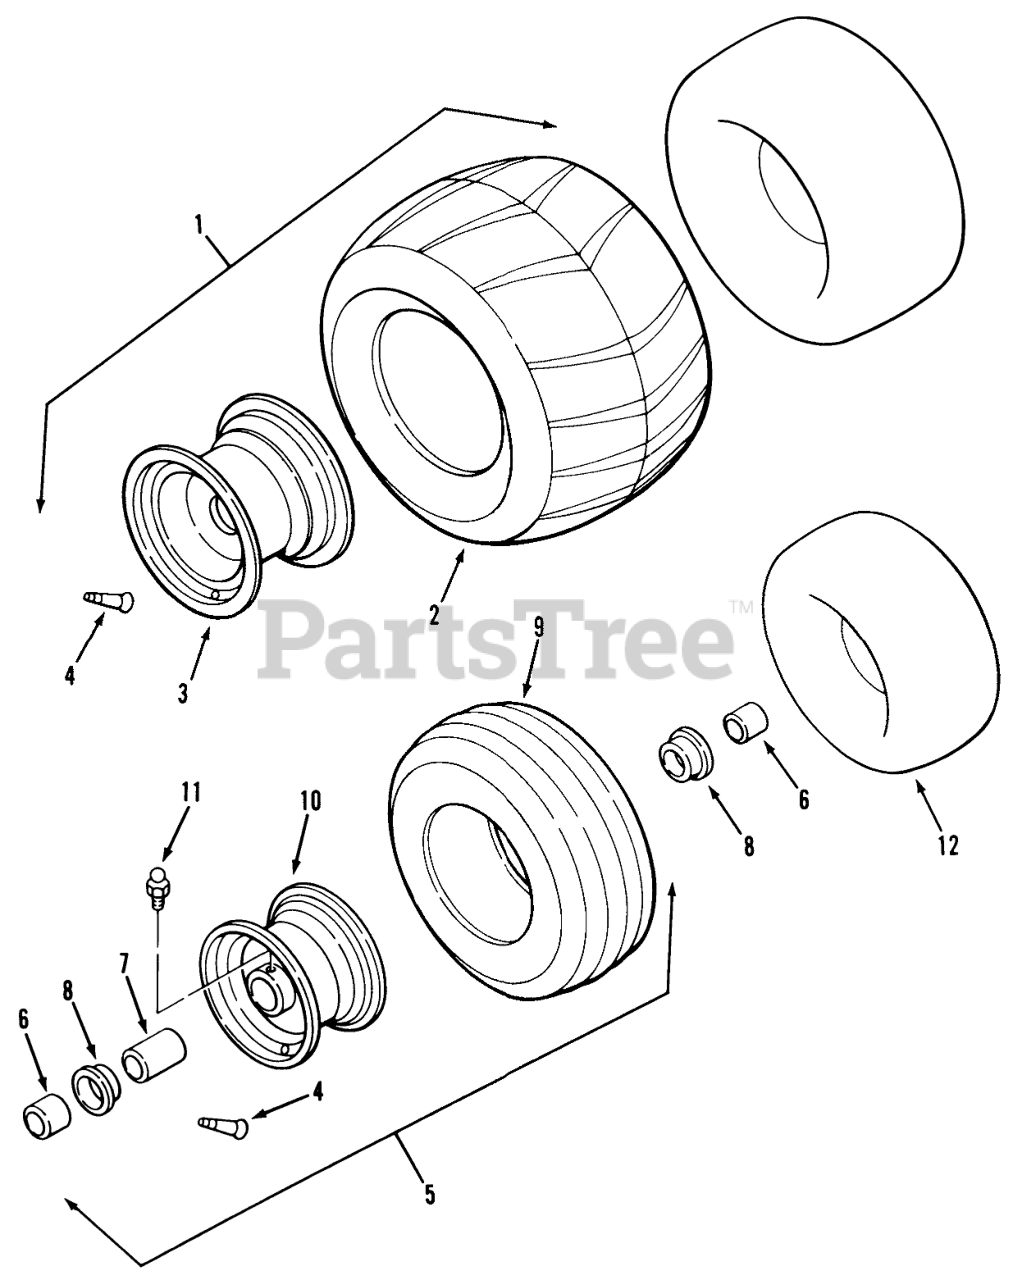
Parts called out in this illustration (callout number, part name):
1	Rear Wheel and Tire 21 x 11.00-8 (Includes items 2, 3, & 4)
2	TIRE 22 X 11.00-8
3	Wheel-Rear, Silver
4	VALVE
5	Front Wheel and Tire Ass-y (Includes items 7, 8, 9 & 10)
6	Tube-Wheel
7	SPACER FRT WHEEL INN
8	BEARING BALL
9	Front Tire 13 x 5.00-6
10	WHEEL FT SLUV 10239K
11	Zerk
12	INNER TUBE
